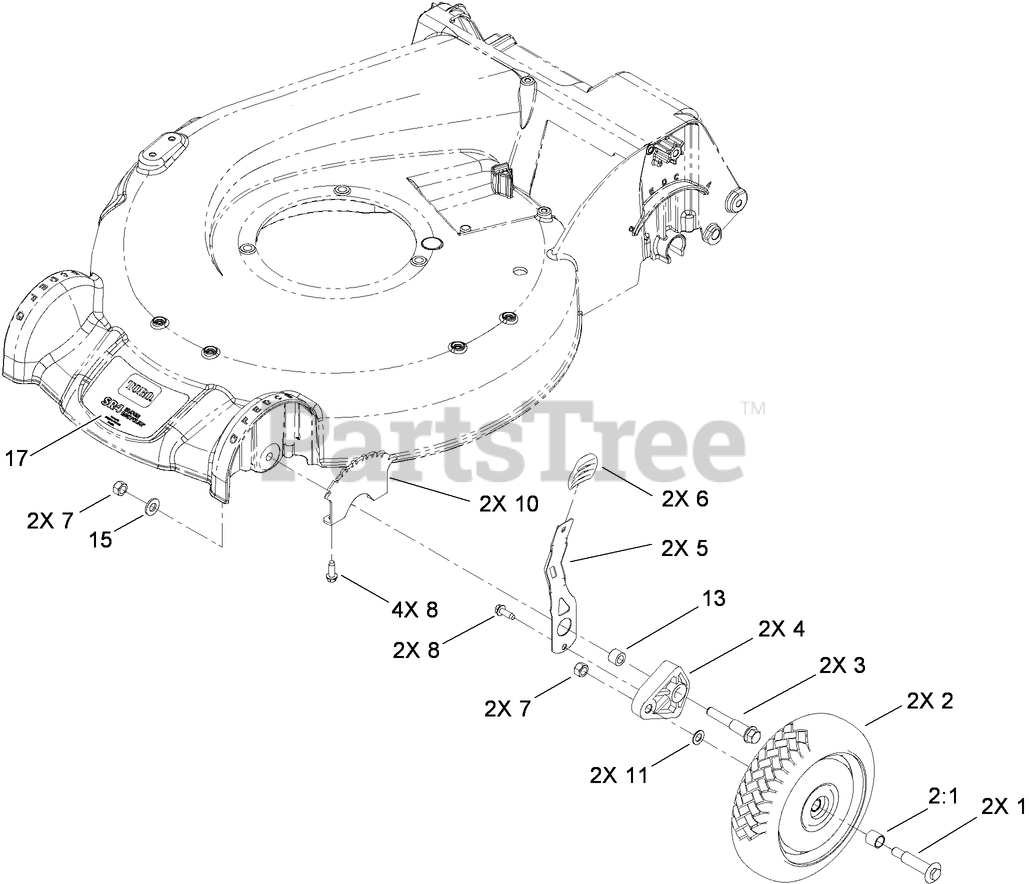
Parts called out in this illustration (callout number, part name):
1	BOLT-SHOULDER
2	WHEEL AND TIRE ASM
2:1	BUSHING
3	SCREW-SHOULDER
4	ARM-PIVOT
5	ARM-SPRING
6	KNOB-LEVER, HOC
7	LOCKNUT
8	SCREW-HWHTF
10	PLATE-HOC
11	WASHER
13	SPACER-WHEEL
15	WASHER-FLAT
17	DECAL-SUPERCARE
